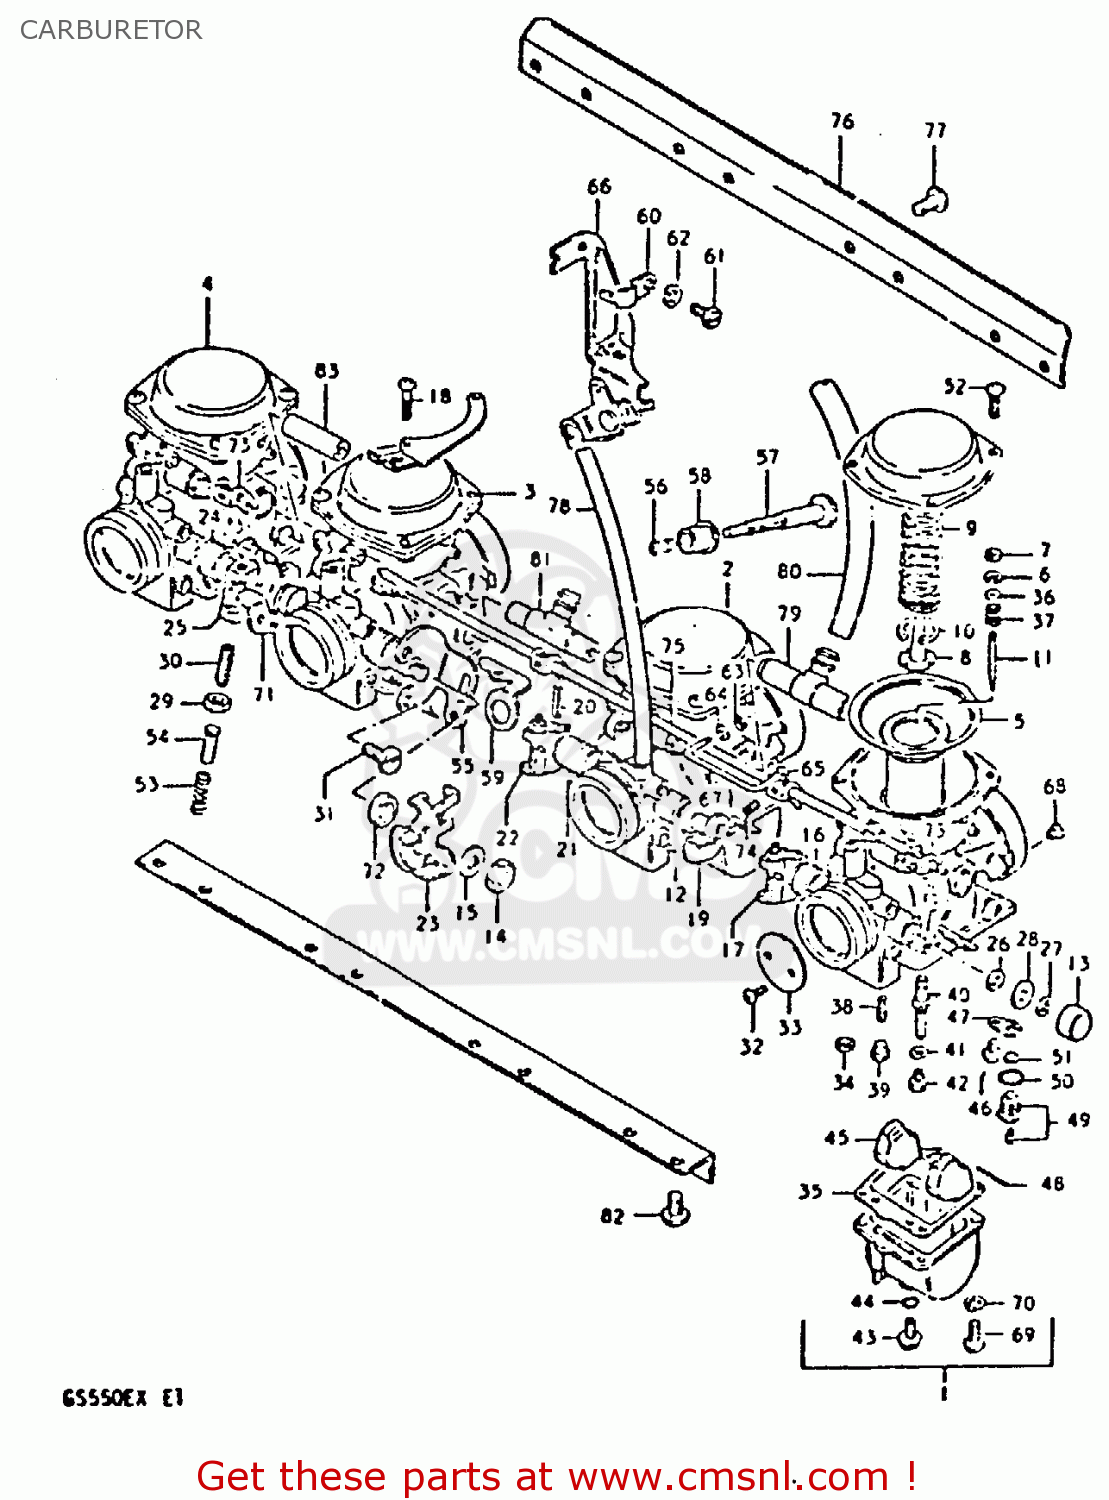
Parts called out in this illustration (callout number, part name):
1	CARBURETOR, NO.1
2	CARBURETOR, NO.2
3	CARBURETOR, NO.3
4	CARBURETOR, NO.4
5	DIAPHRAGM ASSEMBLY
6	CLIP,NEEDLE
7	RING
8	HOLDER,GUIDE
9	SPRING
10	E RING
11	NEEDLE, JET (5F42-3)
12	GASKET,THROTTLE SHAFT (NAS)
13	CAP
14	NUT
15	WASHER
16	SPRING,THROTTLE SHAFT
17	SHAFT,THROTTLE
18	SCREW
19	SHAFT,THROTTLE
20	PIN,THROTTLE SHAFT
21	SPRING,THROTTLE SHAFT
22	LEVER,THROTTLE SHAFT
23	LEVER ASSEMBLY,THROTTLE
24	SPRING,THROTTLE SHAFT
25	SHAFT,THROTTLE
26	SEAL
27	E RING
28	GASKET,THROTTLE SHAFT (NAS)
29	NUT
30	SCREW
31	SCREW,THROTTLE ADJUST B
32	SCREW
33	VALVE,THROTTLE (BUTTERFLY)
34	GASKET (NAS)
35	GASKET,FLOAT CHAMBER (NAS)
36	WASHER
37	SPRING
38	JET
39	PLUG,NEEDLE JET
40	JET, NEEDLE (X-6)
41	WASHER,NEEDLE NOZZLE
42	JET
43	PLUG,DRAIN
44	O RING
45	FLOAT
46	SCREW
47	PLATE
48	PIN,FLOAT
49	VALVE ASSEMBLY,NEEDLE
50	O-RING,NEEDLE VALVE
51	FILTER
52	SCREW
53	SPRING,THROTTLE SCREW
54	PIN,THROTTLE LEVER
55	BRACKET,THROTTLE ADJUST
56	SPRING
57	SCREW
58	BUSH
59	BRACKET,THROTTLE ADJUST
60	BRACKET,STARTER
61	BOLT
62	LOCK WASHER
63	CAP,LEVER
64	SEAT,SPRING
65	LEVER ASSY
66	BRACKET
67	ROD,STARTER LEVER
68	JET,AIR
69	SCREW
70	LOCK WASHER
71	SHAFT,THROTTLE
72	WASHER
73	LEVER
74	SCREW
75	SHAFT,STARTER
76	BRACKET
77	SCREW
78	HOSE
79	NIPPLE
80	HOSE
81	NIPPLE,CARBURETOR
82	SCREW 6X12
83	NIPPLE
